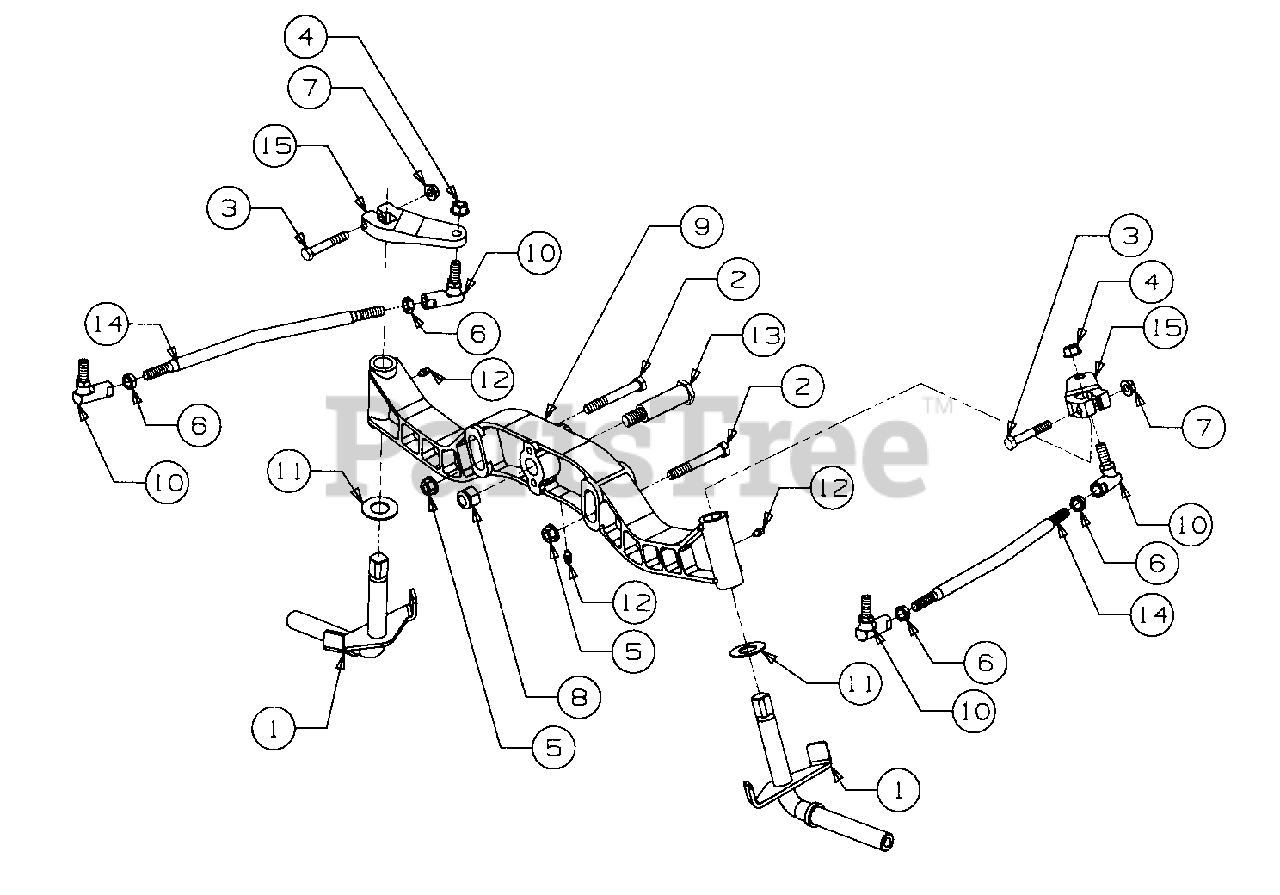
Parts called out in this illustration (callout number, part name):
1	Knuckle Assembly, Steering
2	Screw, Hex Cap, 3/8-16 x 2.75 GR8
3	Screw, Hex Cap, 5/16-18 x 2 GR5
4	Nut, Hex Lock, 3/8-24 GR5
5	Nut, Hex Flanged Lock, 3/8-16
6	Nut, Hex Jam, 3/8-24 GR2
7	Nut, Hex Flange Top Lock, 5/16-18
8	Nut, Hex Top Nylon Lock, 1/2-13
9	Axle, Front Pivot
10	Joint, Ball, 3/8-24
11	Washer, Flat, .760 x 1.49 x .06 Thk.
12	Fitting, Lube, 3/16 Drive Type
13	Bolt, Pivot Shoulder, 3/4 Dia x 2.23
15	Arm, Steering
